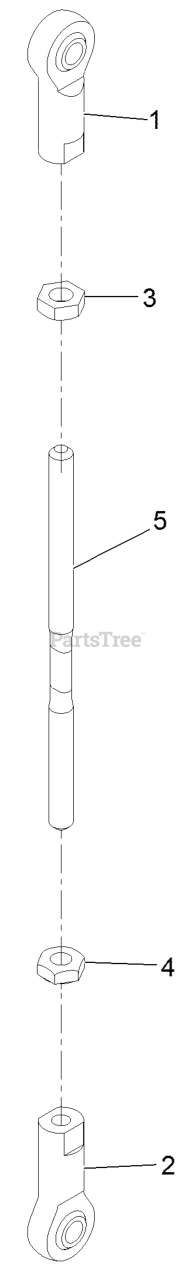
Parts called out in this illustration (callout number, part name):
1	ROD END-BALL JOINT
2	JOINT-BALL, LH
3	NUT-JAM
4	NUT-JAM
